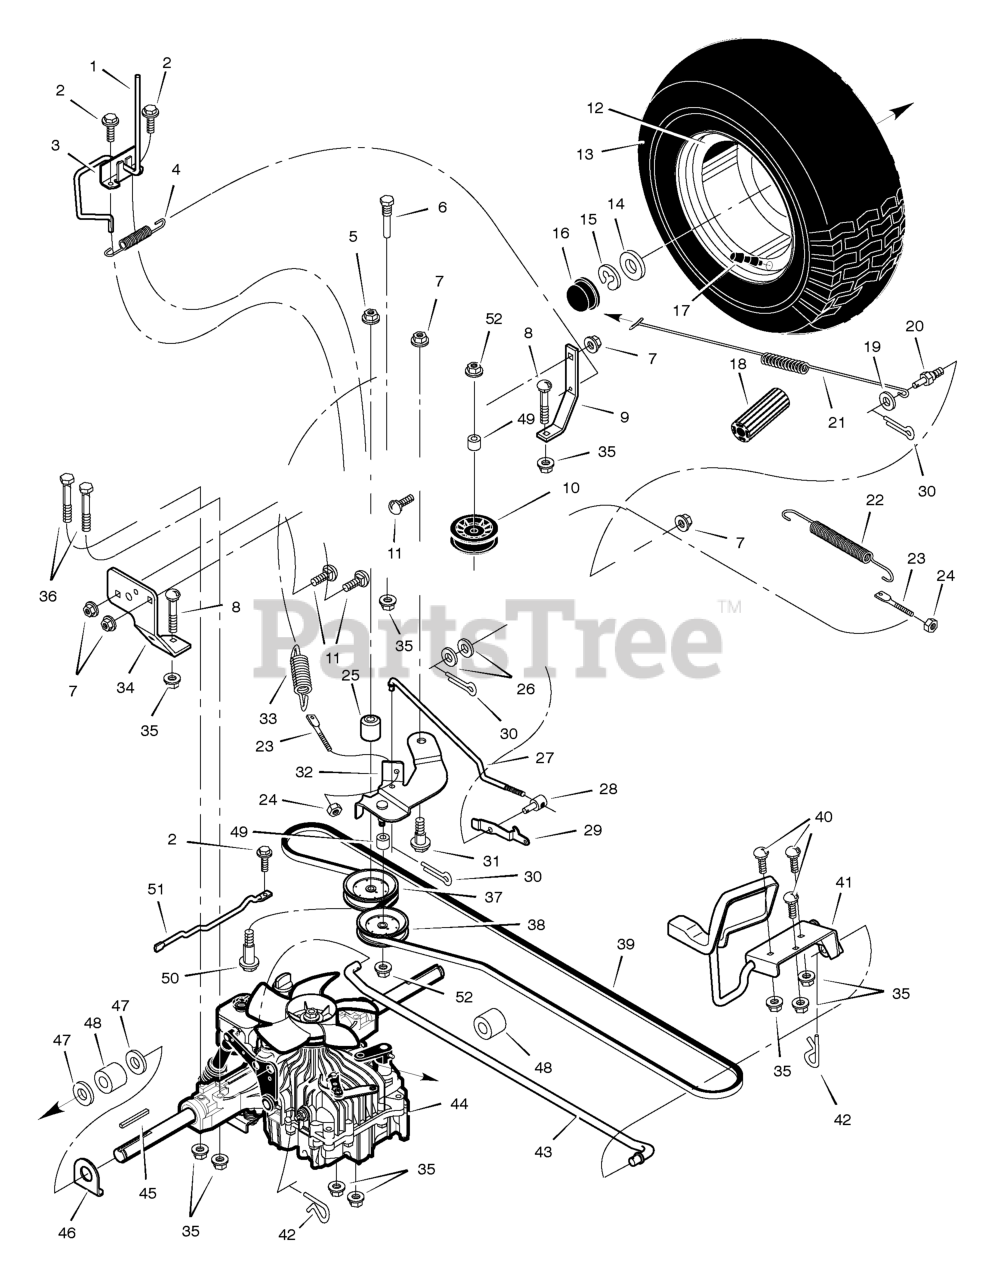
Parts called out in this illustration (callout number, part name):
1	ROD, Clutch
2	CAPSCREW, Hex Head, 5/16-18 x 3/4
3	Bracket, Disconnect
4	Spring - Extension
5	NUT, Lock, 1/2-13
6	Screw, Guide
7	NUT, Hex Flange, Center Lock, 3/8-16
8	BOLT, CARRIAGE - 5/16-18 X 2.00
9	Bracket, Torque
10	Clamp-Casing
11	Bolt, Carriage
12	Assembly, Wheel and Tire
13	Tire Only *
15	E-RING, Retainer
16	HUB CAP
17	VALVE STEM & CAP
18	PEDAL, Clutch and Brake
19	WASHER, Flat, 1
20	Base-Air Cleaner Primer
21	Spring, Extension
22	SPRING, EXTENSION LIFT
23	STUD, Spring Mounting
24	NUT, Hex Flange, 5/16-18
25	SEAL-VALVE
26	WASHER, Flat, 3/8
27	Gasket-Carburetor Plate
28	NUT, Adjusting
29	Latch, Parking Brake
30	COTTERPIN, 3/4
31	BOLT, Shoulder, 3/8-16 x 1/2
32	Assembly, Idler Arm
33	SPRING, Extension
34	Bracket, Torque
35	NUT, Hex Flange, Center Lock, 5/16-18
36	BOLT, Hex, 5/16-18 x 2-1/2
37	Pulley, Backside Idler
38	PULLEY, Idler, 3"
39	Belt, Drive
40	BOLT, Carriage, 5/16-18 x 5/8
41	Pedal Assembly, Hydro
42	PIN, Hair
43	Spring-Governor
44	Transaxle, Hydro **
45	Key, Square
46	Washer, Thrust
47	WASHER, 1-1.3 16G FLT
49	SPACER, 1/2 in To 17 mm
51	SPACER
52	NUT, Hex Flange, Center Lock, 3/8-16
